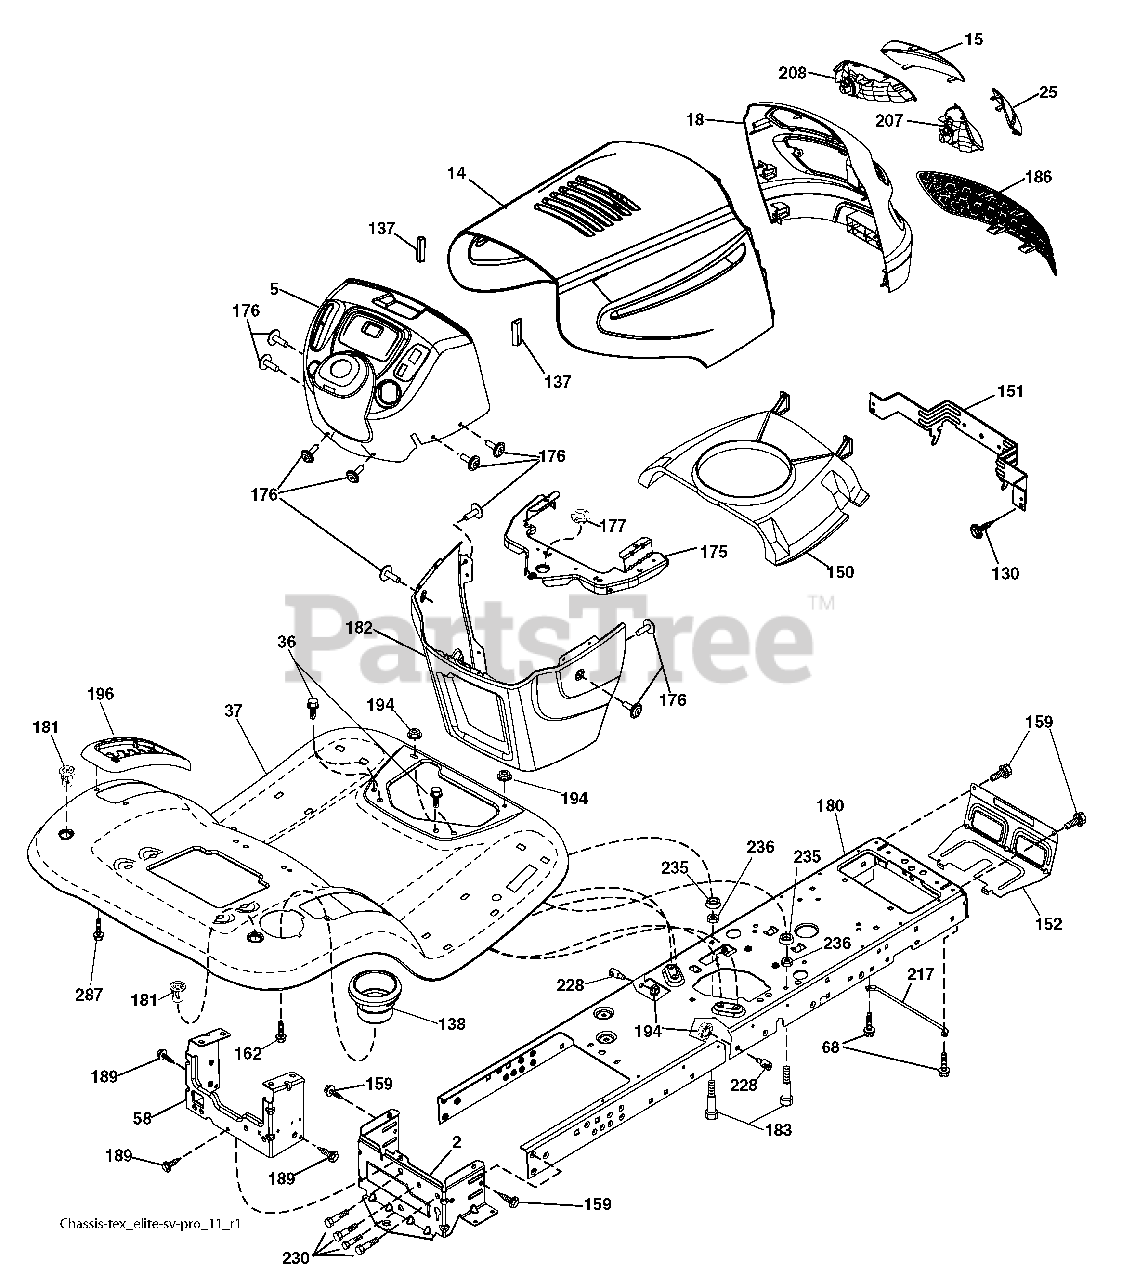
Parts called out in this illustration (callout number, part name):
2	Drawbar Lower
5	Dash
14	Hood
15	Lens Grille LH
18	Grille
25	Lens Grille RH
36	Screw 5/16-18 x 3/4
37	Fender
58	Drawbar Upper
68	Screw Thdrol 5/16-18 x 1/2
130	Screw #10 x 0.750
137	Bumper Hood
138	Cupholder
150	Duct Heat Hood
151	Bracket Pivot
152	Shield Browning/Debris
159	Screw Hexwsh Thdrol 3/8-16 x 3/4
162	Screw Hex Wsh Hi-Lo 1/4 x 1/2
175	Crossmember
176	Screw 10-24 x 5/8 Wshd Qdrx
177	Bushing Steering
181	Bushing Mtg. Fender Crgo.
182	Dash Lower
183	Bolt Fin Hex 5/16-18 x 1-1/4
189	Screw 5/16-18 x 3/4
194	Nut Lock Hex Flange 5/16-18
196	Console Asm. Deck Lift
207	Bezel Grille RH
208	Bezel Grille LH
217	Rod Pivot Hood
228	Stud Fastener
230	Bolt Shoulder 5/16-18
235	Spacer Fender
236	Nut center Lock 5/16-18
287	Screw 1/4-20 x 3/8
